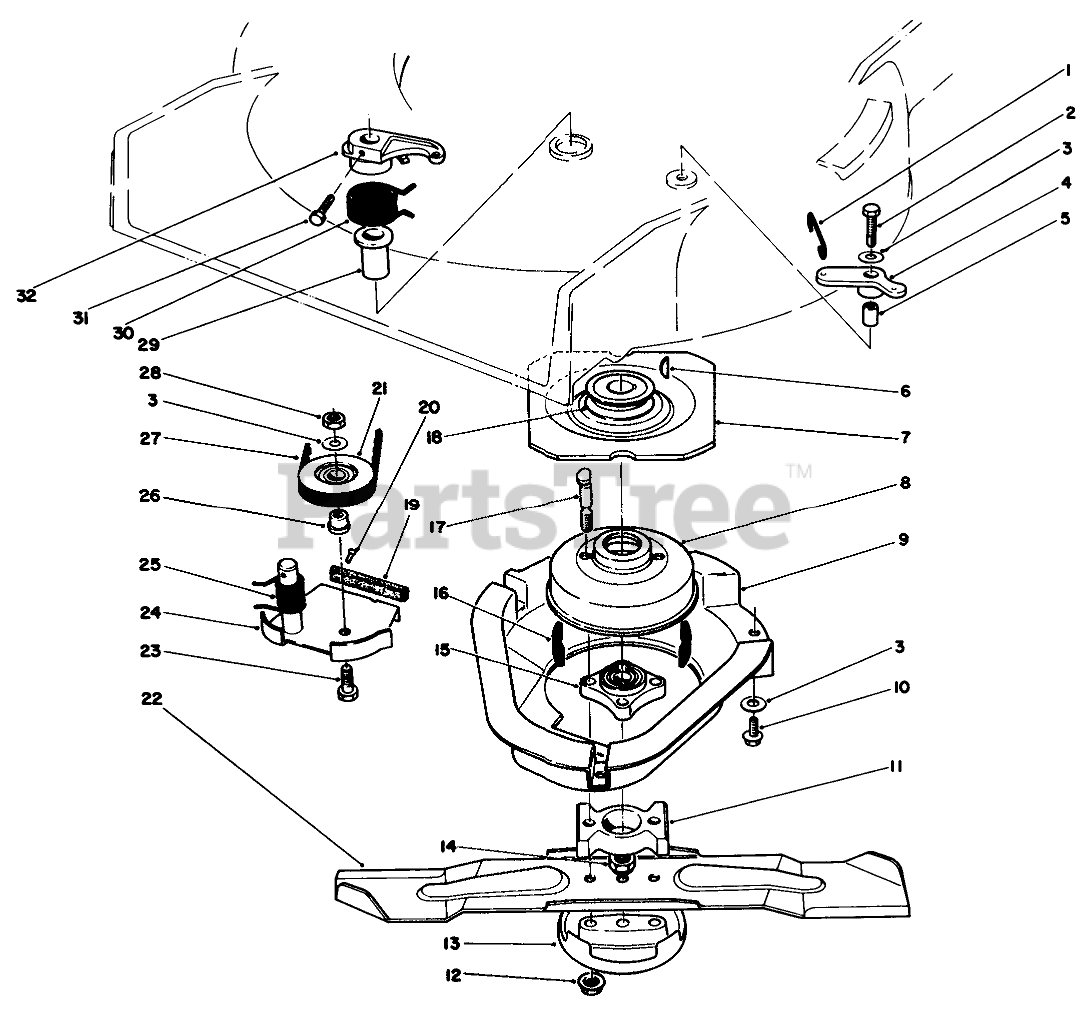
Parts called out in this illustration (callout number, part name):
1	LINK-CONTROL
2	SCREW-HH
3	WASHER-PLAIN
4	BELLCRANK
5	SLEEVE-BELLCRANK
6	KEY-WOODRUFF
7	Flywheel
8	Drum-Brake
9	SHIELD BBC
10	SCREW-HWHTF
11	Spacer Blade
12	NUT-LOCK
13	Anti Scalp Cup
14	NUT-LOCK, NI
15	HUB ASM
16	DAMPENER-VIBRATION
17	BOLT-BLADE
18	PULLEY-DRIVER
18	PULLEY
19	Pad-Brake
20	.185 DIA X .375 RT +
21	PULLEY-IDLER
22	BLADE-21in
23	SCREW-HH
24	Brake Plate (Incl. Ref. #19 & 20)
25	SPRING-TORSION
26	HUB-PULLEY, IDLER
27	V-BELT
28	NUT-LOCK, NI
29	BUSHING PM
30	SPRING-TORSION
31	SCREW-HH
32	LEVER
